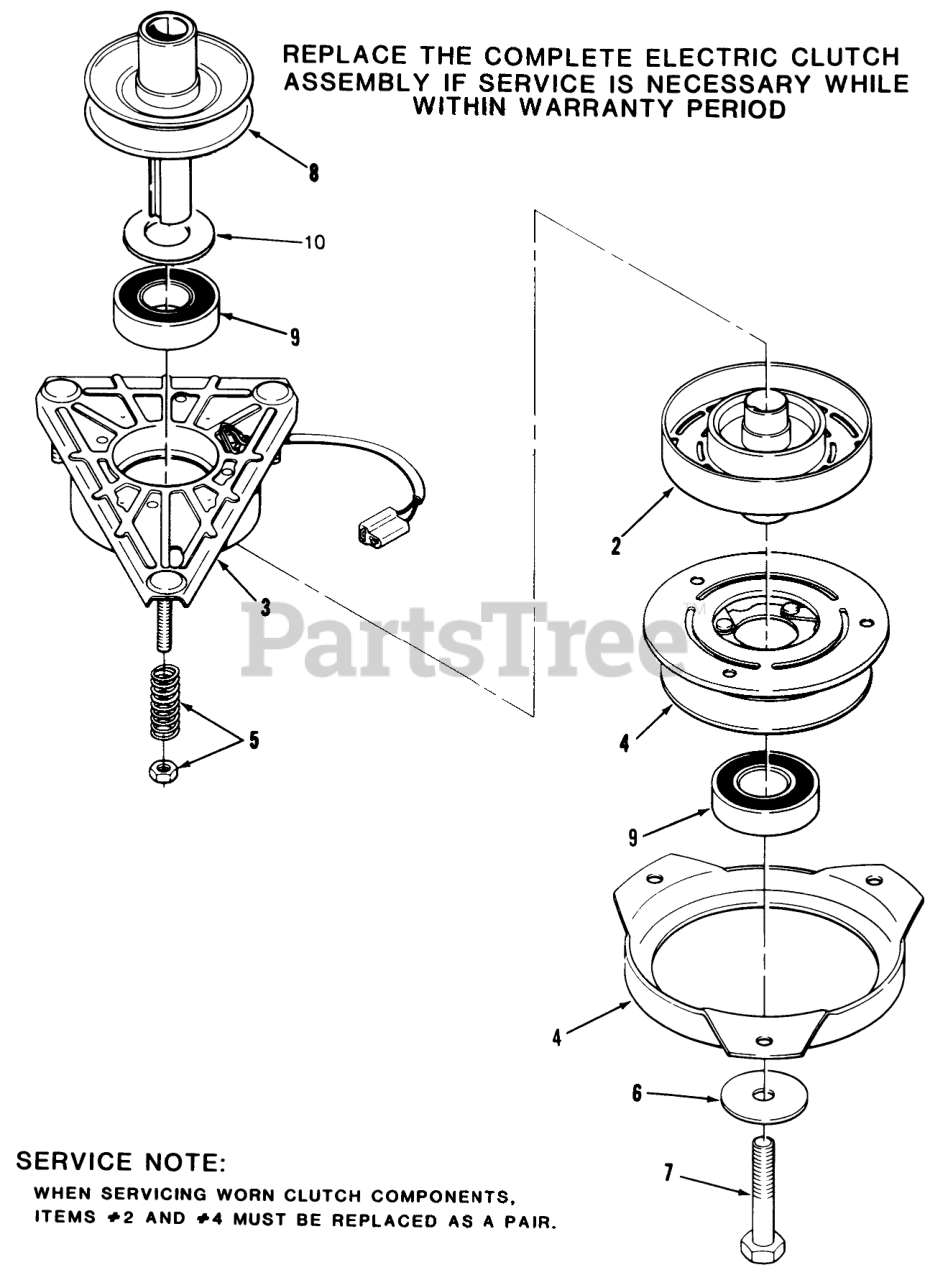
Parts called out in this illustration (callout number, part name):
1	Electric Clutch Assembly (Inc. Ref. #2, 3, 4 & 5)
2	ASS'Y-ROTOR
3	Field Assembly (Incl. one of Ref. #9)
4	Armature and Pulley Assy (Incl. one of Ref. #9 and Brake Plate)
5	ACCESS SPRING & NUT
6	WASHER
7	HHCS-M10X1.5X110 ESL
8	PULLEY-ENGINE
9	BEARING-ELEC CLUTCH
10	WASHER
